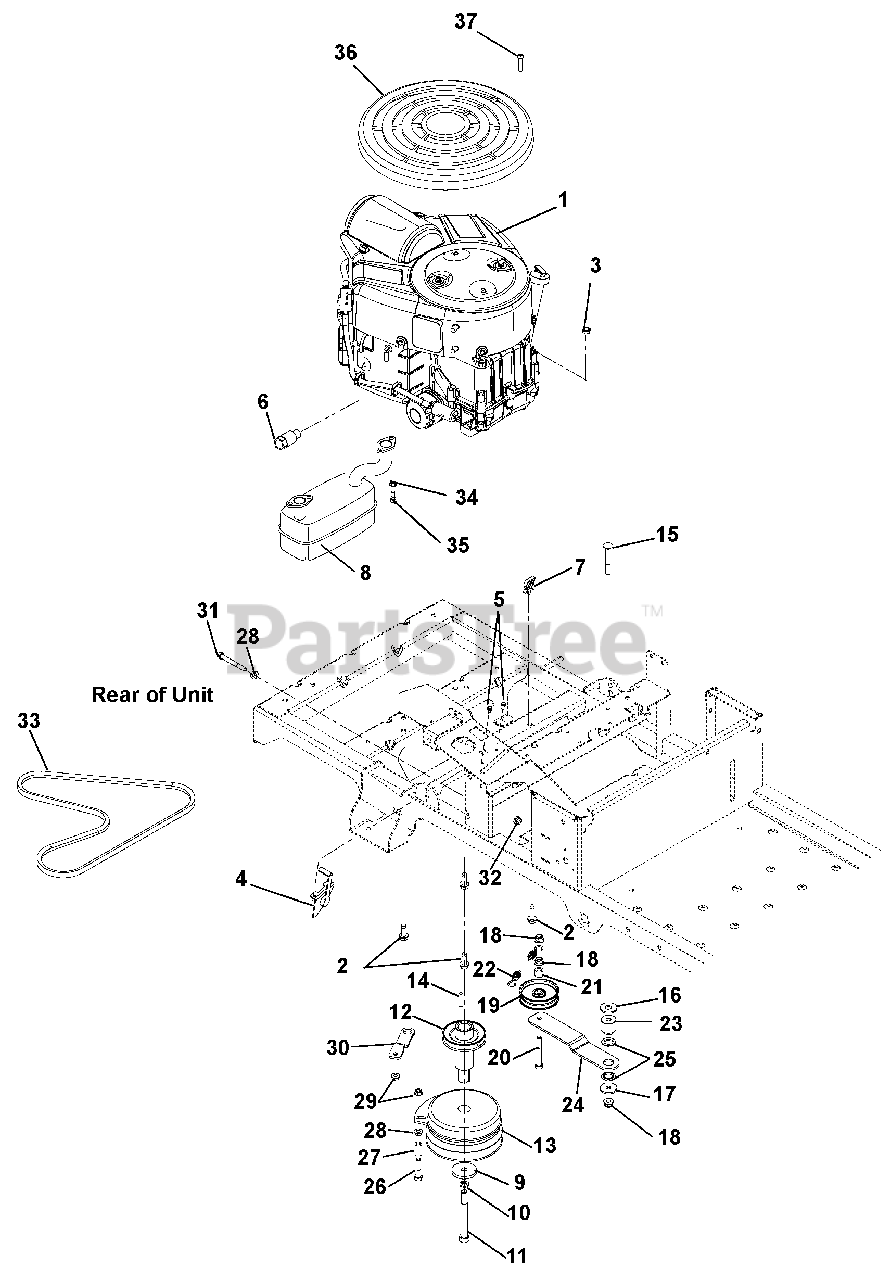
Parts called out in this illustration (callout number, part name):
1	ENGINE, 16HP V-TWIN CE
2	@SCR-TAP .38-16X1.25 HWH TR YZ
3	@NUT-LK-CTR-JAM .375-16 YWZC
4	CABLE, CHOKE/THROTTLE COMBO
5	@SCR-TAP 10-24X.50 HWH TR YWZC
6	DRAIN, OIL
7	WIRE CLIP
8	MUFFLER - TWIN BRIGGS
9	WSHR-FL-STL .469X2.00X.25 YWZC
10	@WSHR-LK .44X.109 REG YWZC
11	BLT-HEX .44-20X4.50 GR8 YWZC
12	WMT-PTO EXTENSION W/SHEAVE
13	CLUTCH, 105 FT*LB MONO POLE
14	KEY-SQ .25 X 1.25 X .25 SAE
15	@BLT-RDHDSQNK .38-16X2.75 G5YZ
16	@WSHR-FL-STL.563X1.38X.109YWZC
17	WSHR-FL-STL .406X1.375X.135 YZ
18	@NUT-LK-NYL-FLG .38-16 YWZC
19	PULLEY, ENGINE CLUTCH 03608
20	@BLT-HEX .38-16X2.75 GR5 YWZC
21	BSHG-SLV .391X.688X.52 PM
22	SPRING, EXTENSION
23	SPACER, GROUND DRIVE IDLER
24	IDLER ARM, GROUND DRIVE
25	BUSHING, IDLER ARM
26	SCR-CAP .31-18X1 3/4 S/HD YWZC
27	SPACER, RUBBER 5/16 IDX1.0 LG
28	@NUT-SPNLK-FLG .312-18 YWZC
29	@NUT-LK-TOP-FLG .31-18 YWZC
30	BRKT, CLUTCH STOP
31	@BLT-HEX .31-18X2.75 GR5 YWZC
32	@NUT-LK-NYL-FLG .31-18 YWZC
33	V-BELT, HA-RAW EDGE
34	@WSHR-LK .31X.078 REG YWZC
35	SCR-CAP .31-18X.75 S/HD
36	GUARD, BRIGGS ENGINE
37	SCREW, 8-16X.87 PHPAN 3 LOBE
